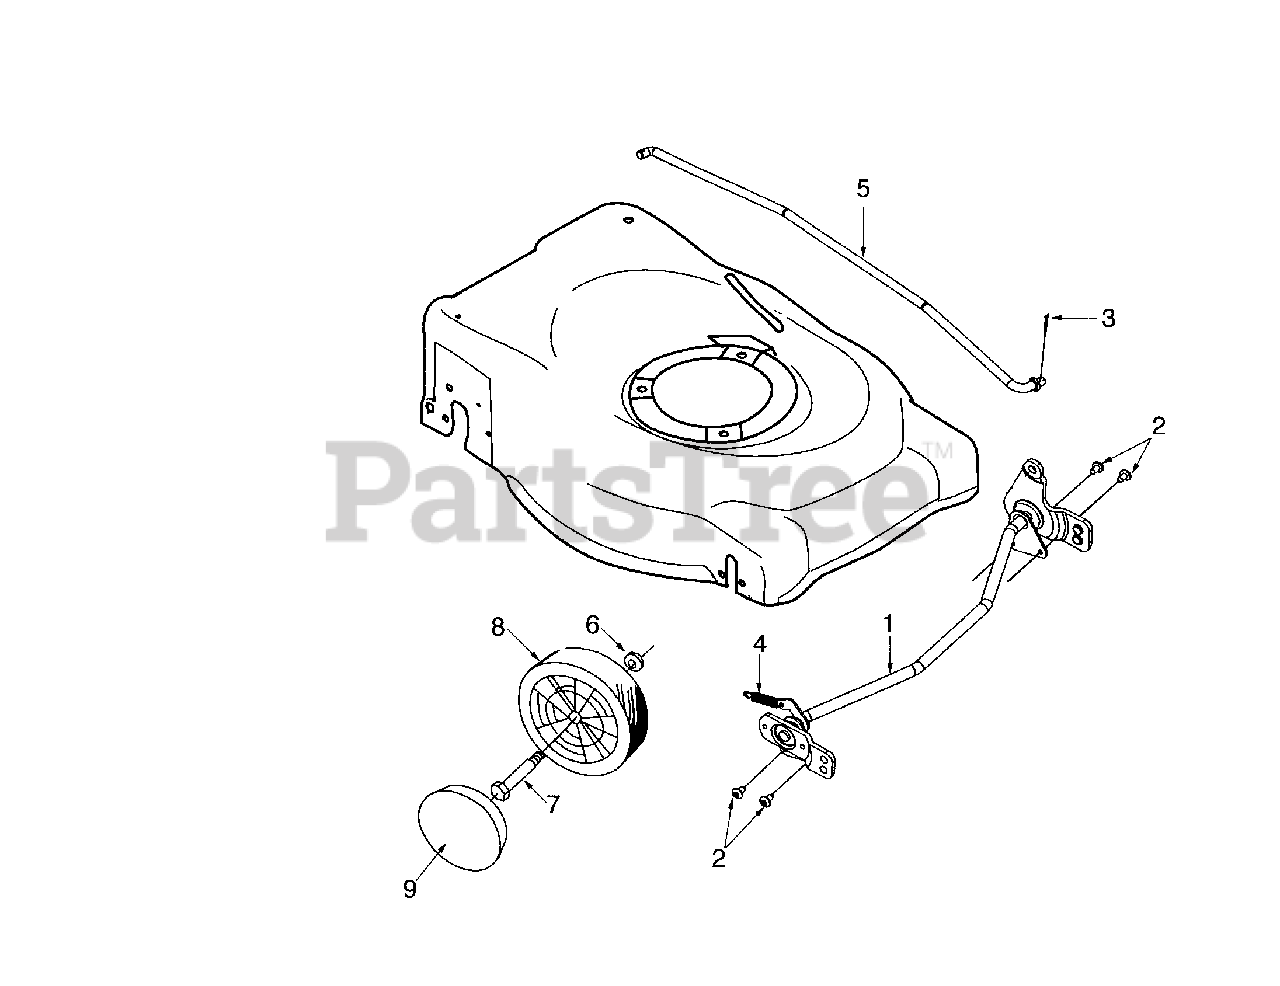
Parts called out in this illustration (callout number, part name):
2	AB Pan Scr. 1/4-14 x .50 Lg.
3	Cotter Pin 3/32 x .750
4	Ext. Spring
5	Adj. Rod
6	Spr. Washer
7	ShI. Bolt .498 x 1.445 3/8-16
8	Front Wheel Bar Tread 8" x 1.75"
9	Gray (3-1/2" Dia) Hub Caps
